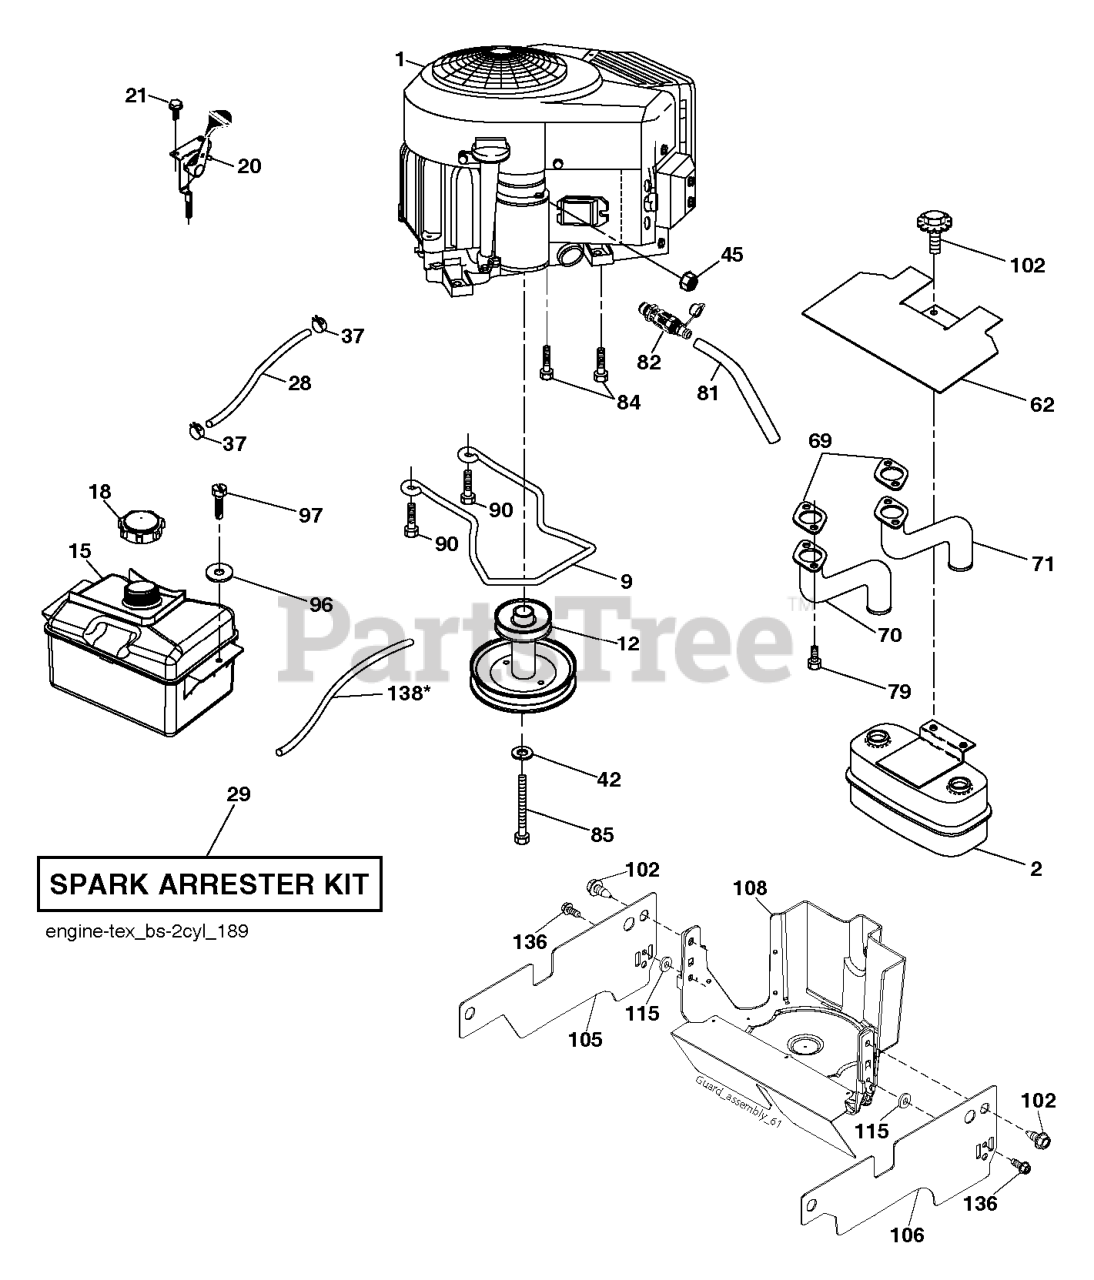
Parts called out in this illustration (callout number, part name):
2	MUFFLER.ASM.TWIN.MNTG.BRACKET
12	ENGINE.PULLEY
15	Tanks
15	FUEL.TANK.ASM.NON-EPA
18	CAP ASM.FUEL.2.25"FR.
20	THROTTLE CABLE
28	LINE.FUEL.20
29	KIT.SPARK ARRESTOR 794945 B&S
37	HOSE CLAMP
62	SHIELD.HEAT.MUFFLER
69	GASKET.MUFFLER
70	EXHAUST.TUBE.LH.BS/TWIN
71	EXHAUST.TUBE.RH.B&S.TWIN.INTEK
81	TUBE, DRAIN OIL ASM.
82	VALUE.OIL.DRAIN
84	SCREW.3/8-16
85	BOLT.HEX.7/16-20X4.GR5.1.5BLUE
90	SCREW 3/8-16X1
97	SCREW HEXWSHR 1/4-20X3/4
102	SCREW
105	SHIELD.SIDE.LH.3842"TEX FRN.BK
106	SHIELD.SIDE.LH.3842"TEX FRN.BK
108	COVER ENGINE PULLEY COVER WITH
